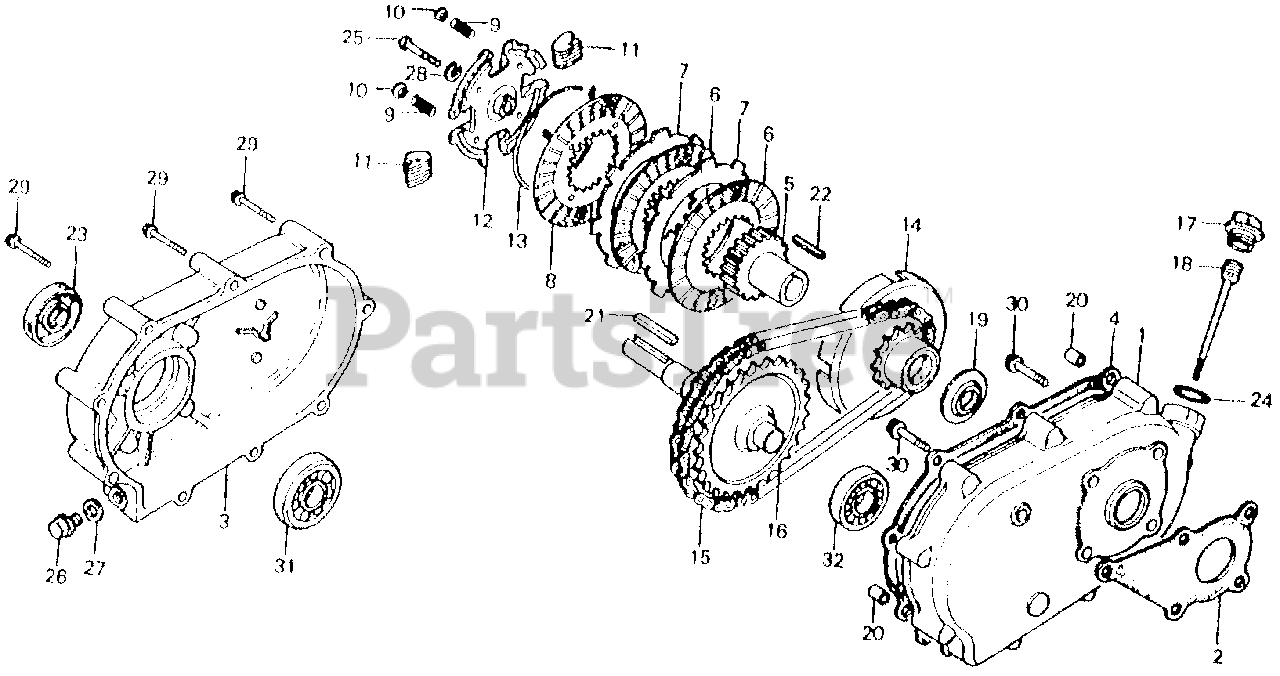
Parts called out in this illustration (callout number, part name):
1	CASE, REDUCTION
2	GASKET, REDUCTION CASE
3	COVER, REDUCTION
4	GASKET, REDUCTION
5	CENTER, CLUTCH
6	DISK, CLUTCH FRICTION
7	PLATE, CLUTCH
8	PLATE, CLUTCH PRESSURE
9	SPRING, CLUTCH FREE
10	HOLDER, CLUTCH SPRING
11	WEIGHT, CLUTCH
12	HOLDER, CLUTCH WEIGHT
13	CENTER, CLUTCH WEIGHT
14	SPROCKET, DRIVE
15	CHAIN, DRIVE (RK428SH-36LE)
16	SHAFT, P.T.O. (28T)
17	CAP, REDUCTION OIL
18	DIPSTICK, OIL
19	WASHER, THRUST (20MM)
20	PIN, DOWEL (8X10)
21	KEY (7X7X33)
22	KEY (5MM)
23	OIL SEAL (PJ30507)
24	O-RING (26X2.7)
25	BOLT, HEX. (8X36)
25	BOLT, HEX. (8X35)
26	BOLT, DRAIN PLUG (12MM)
27	WASHER, DRAIN PLUG (12MM)
28	WASHER, SPRING (8MM)
29	BOLT, FLANGE (6X55)
30	BOLT, FLANGE (8X20)
30	BOLT, FLANGE (8X22)
31	BEARING, RADIAL BALL (6205)
32	BEARING, RADIAL BALL (6206)
